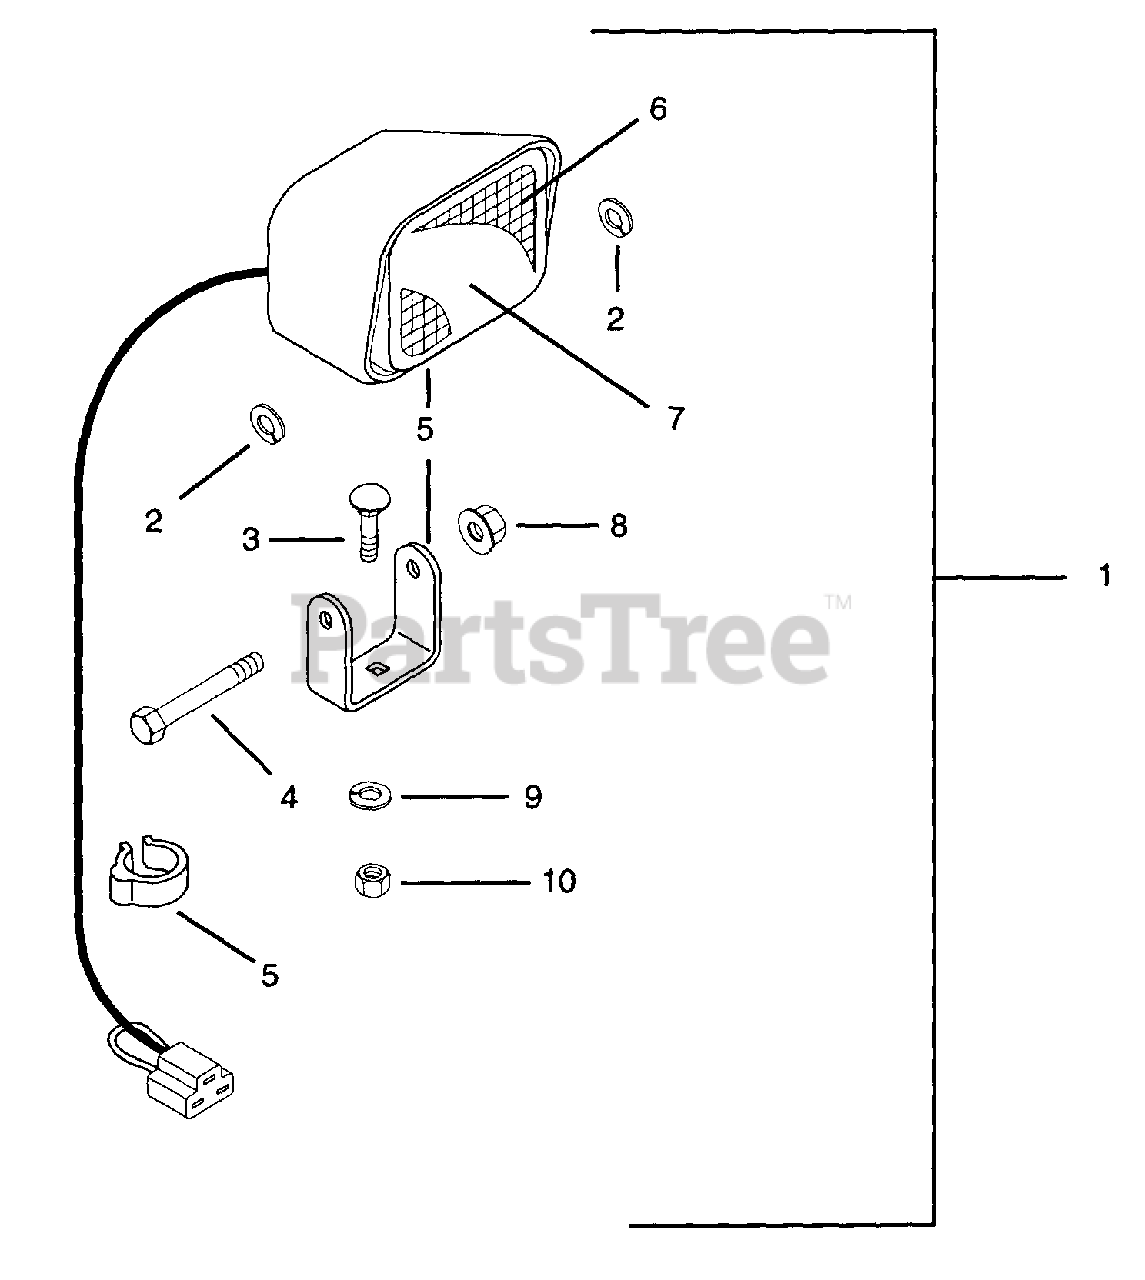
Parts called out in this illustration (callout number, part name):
1	HEADLIGHT
2	@WSHR-LK-EXT.326X.599X.031YWZC
3	BLT-RDHDSQNK .31-18X1.00 PL
4	BLT-HEX .31-18X2.50 PL GR2
6	LENSE-FLOOD
8	@NUT-SPNLK-FLG .312-18 YWZC
9	WSHR-LK .312X.097 HVY YWZC
10	@NUT-HEX .31-18 YWZC
